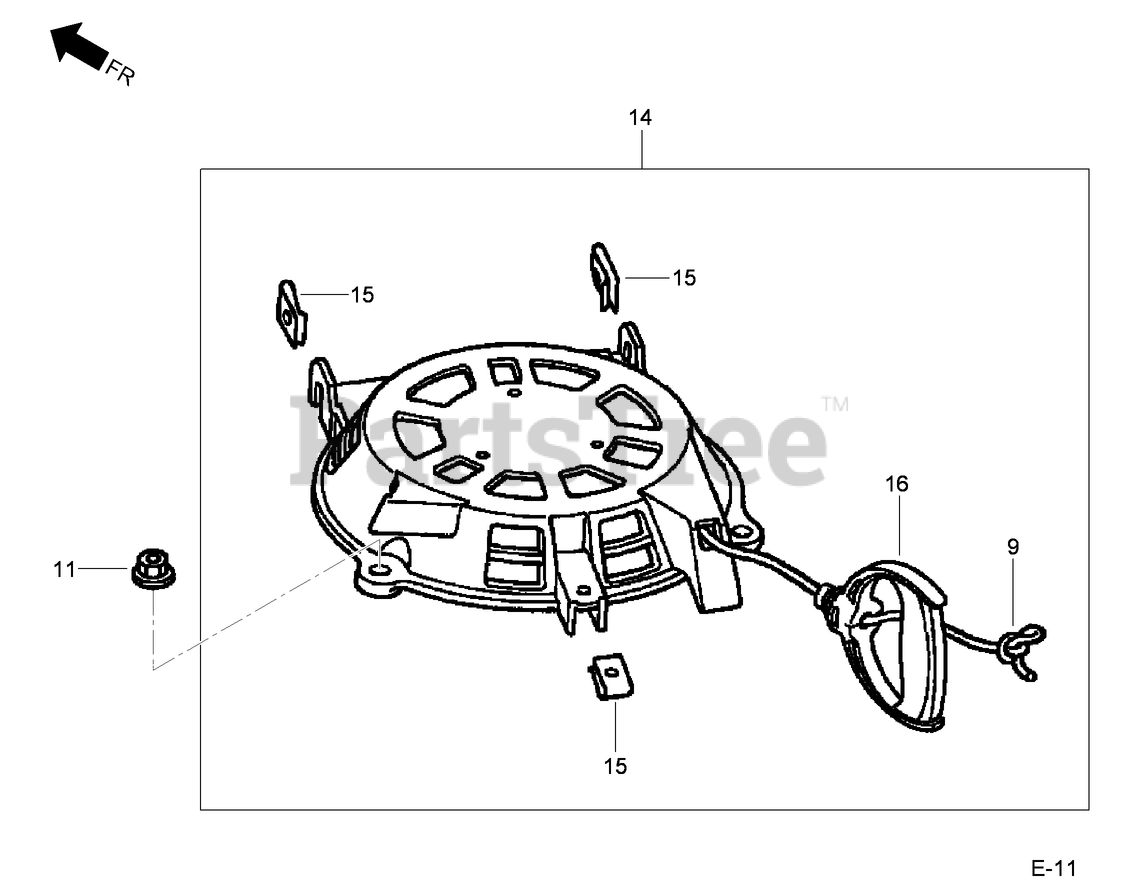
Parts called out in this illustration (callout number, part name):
9	ROPE-STARTER, RECOIL (LONG TYPE)
11	NUT-FLANGE (6MM)
14	RECOIL STARTER ASM (LONG ROPE)
15	NUT-COWL
16	KNOB-STARTER, RECOIL
